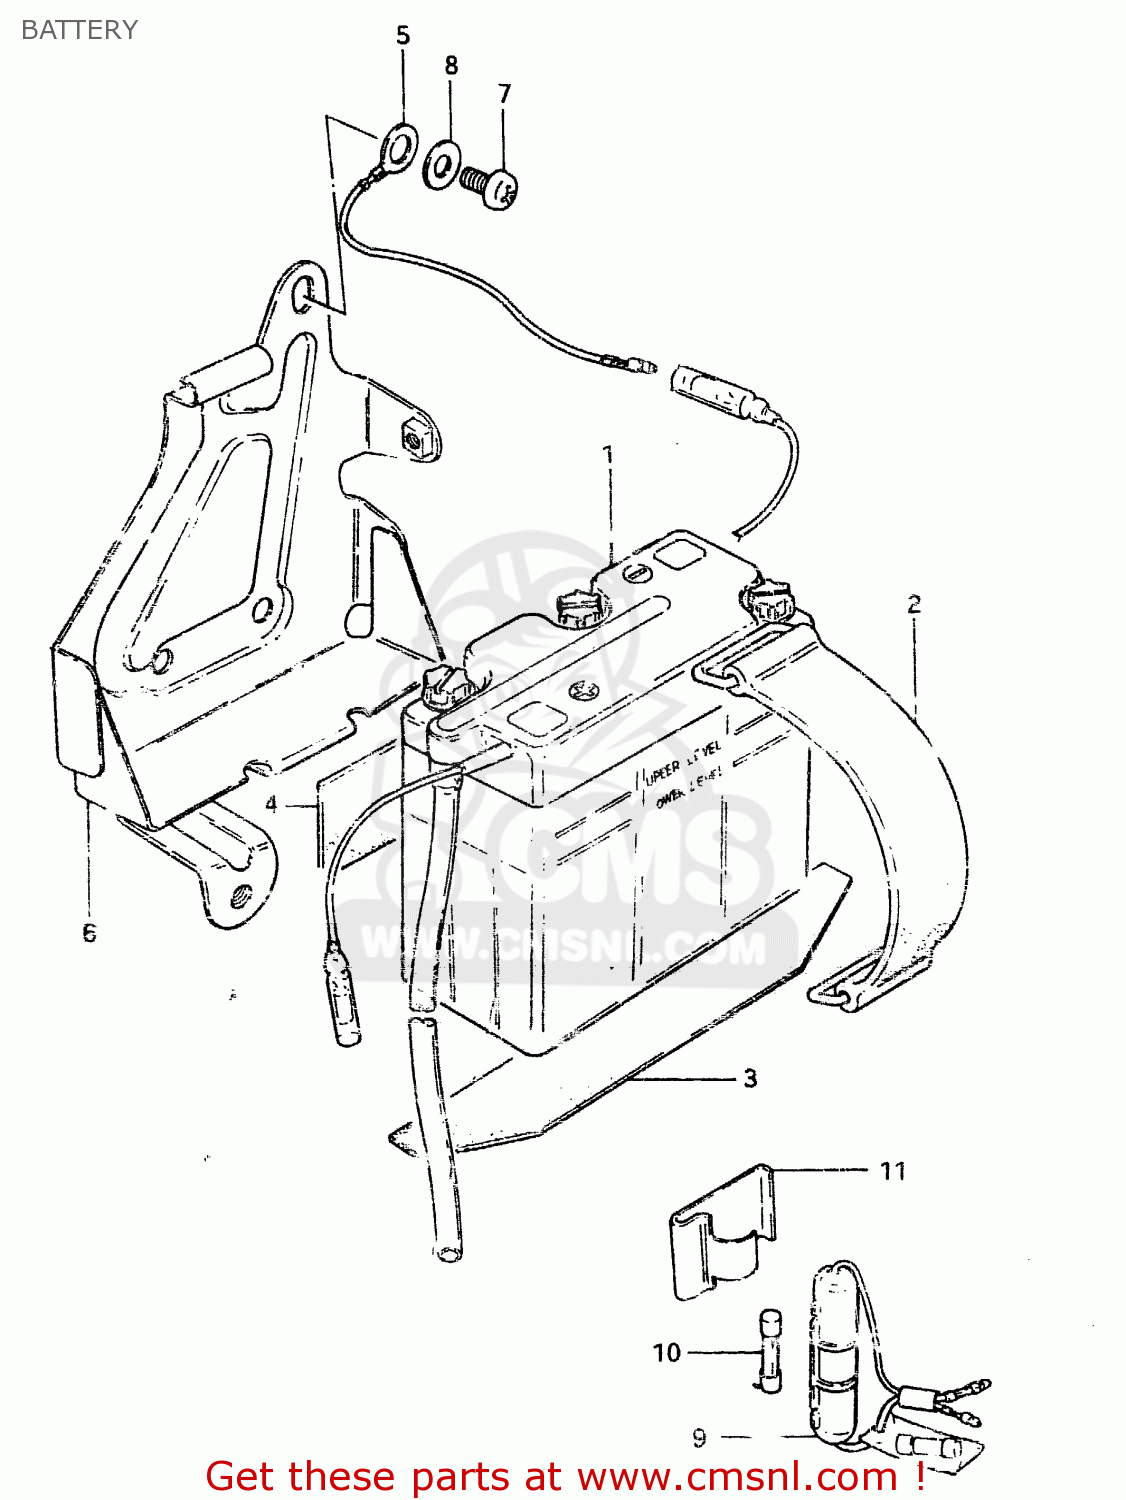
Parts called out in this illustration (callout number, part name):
1	BATTERY(6N4B-2A,6V4.2AH)
2	BAND
3	PROTECTOR,BATTERY
4	PROTECTOR(30X80X2)
5	LEAD WIRE
6	HOLDER, BATTERY
7	SCREW 6X12
8	WASHER
9	BOX ASSEMBLY,FUSE
10	FUSE(10A)
11	HOLDER,FUSE CASE
